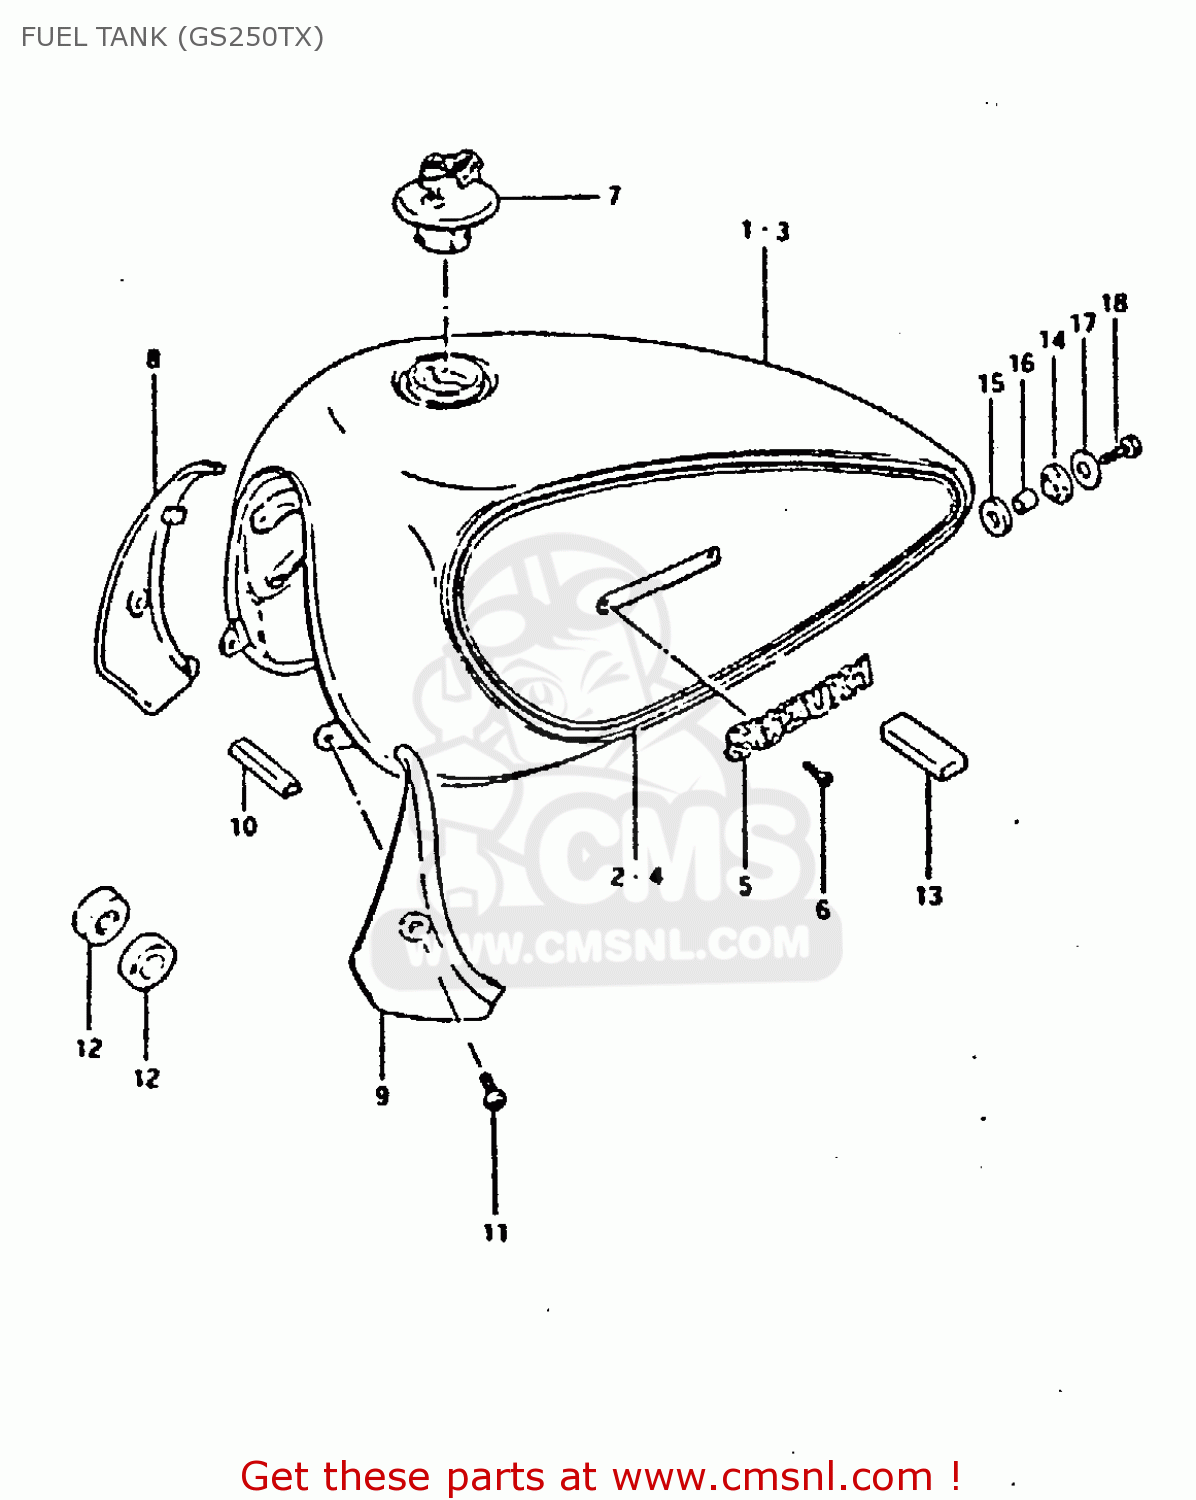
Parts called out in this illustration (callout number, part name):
1	TANK ASSEMBLY,FUEL
2	TAPE SET,FUEL TANK
3	TANK ASSEMBLY,FUEL
4	TAPE SET,FUEL TANK
5	EMBLEM,FUEL TANK
6	SCREW 3X6
7	CAP SET,FUEL TANK
8	COVER,FUEL TANK,FRONT,RIGHT
9	COVER,FUEL TANK,FRONT,LEFT
10	TUBE, FRONT
11	SCREW 6X12
12	CUSHION
13	CUSHION
14	CUSHION
15	CUSHION
16	SPACER(8.5X12X19)
17	WASHER (8.5X29X1.6)
18	BOLT
